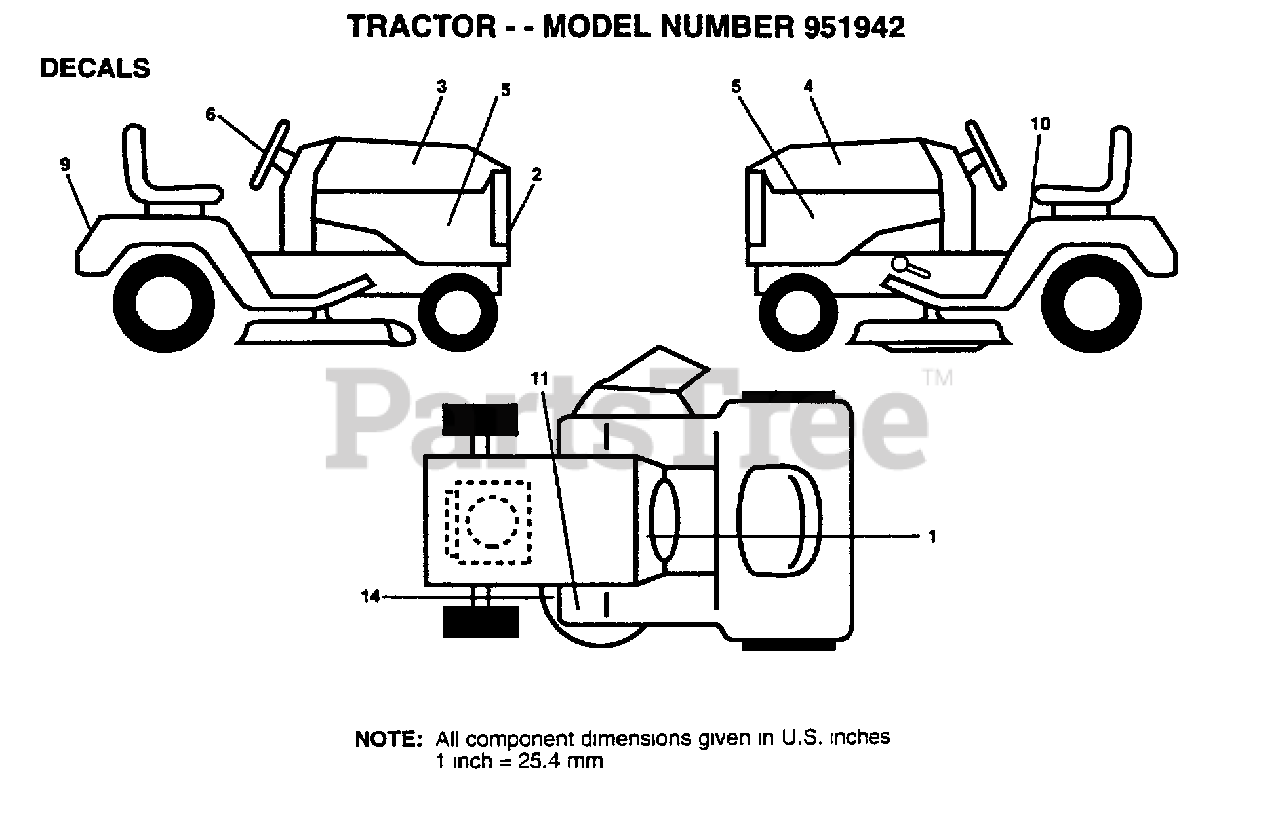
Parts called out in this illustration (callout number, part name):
1	DECAL.DASH.INST.
2	DECAL.GRILL.YARDP
4	DECAL HOOD LH
5	DECAL.PANEL.SIDE
6	DECAL.INS.WHL.STG
10	DECAL
14	"DECAL.V.BELT.44"""
